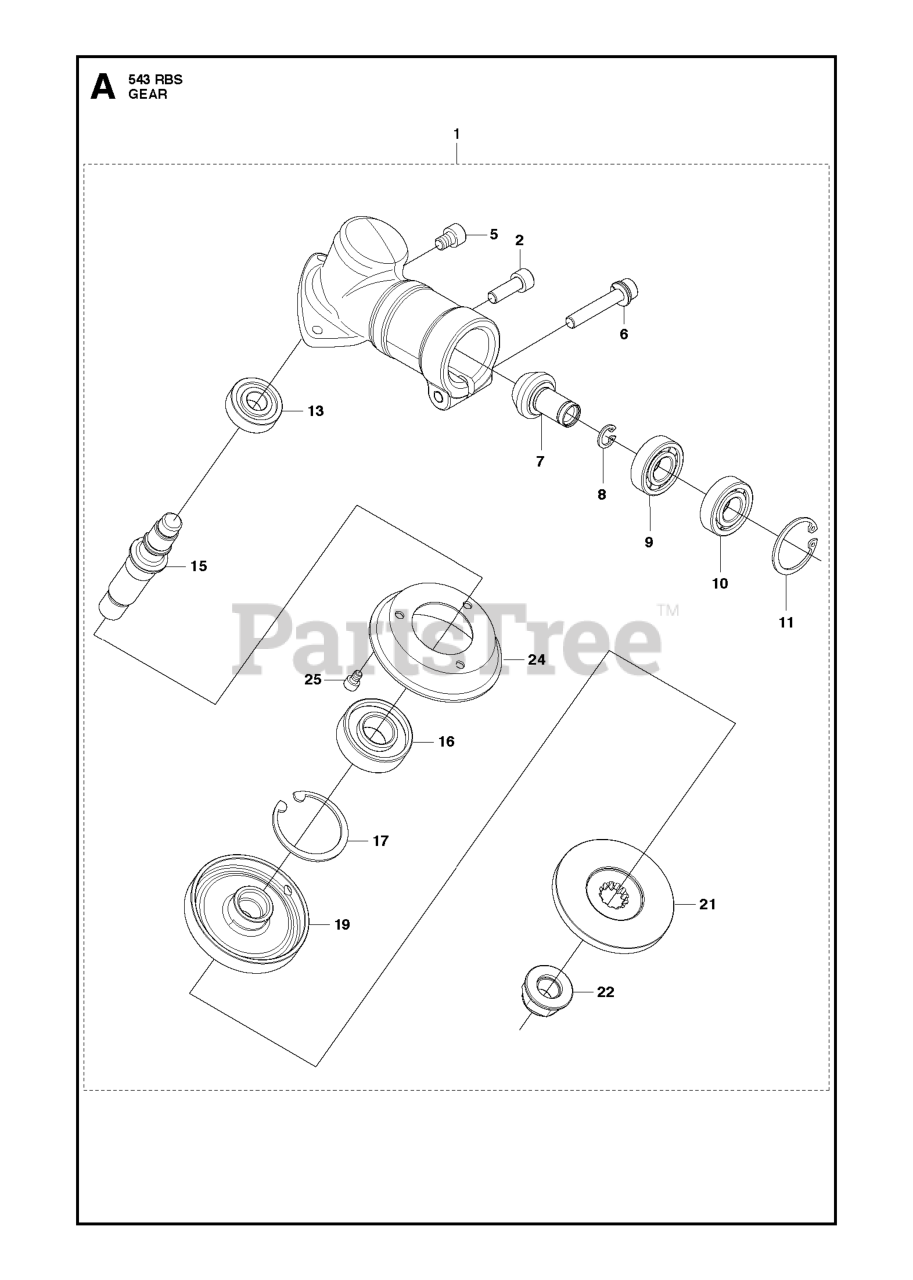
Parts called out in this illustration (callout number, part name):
8	RING
11	RING,SNAP M26x1.2 RP-318013340
16	BEARING***
25	BOLT M5 X L10 ALLEN BOLT
